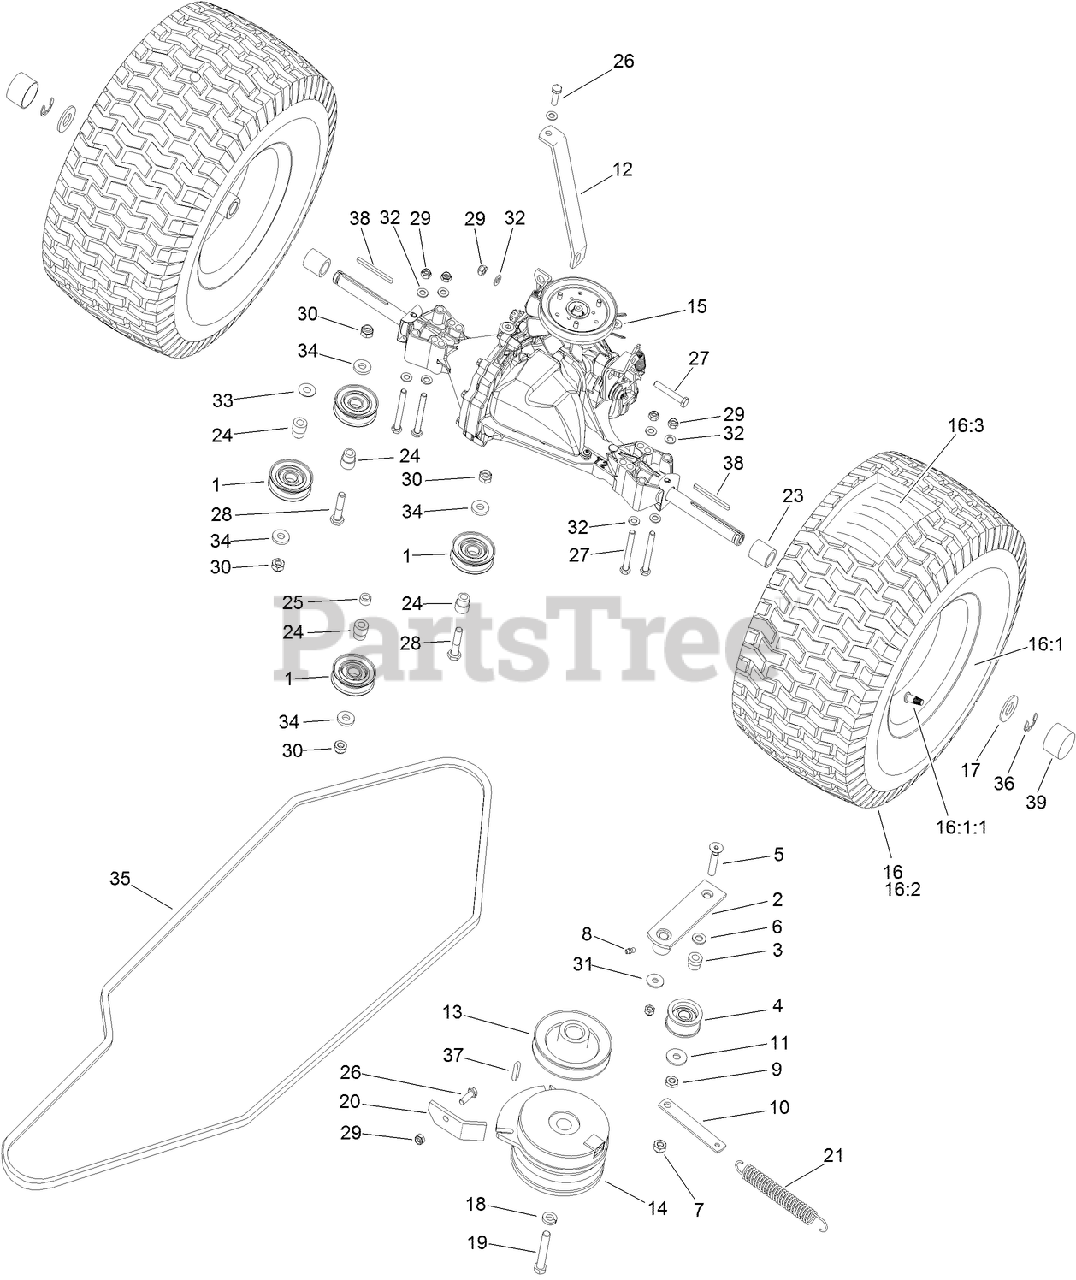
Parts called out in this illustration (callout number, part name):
1	PULLEY-IDLER
2	ARM-IDLER
3	BUSHING-IDLER
4	PULLEY-IDLER
6	WASHER-FLAT
7	NUT-LOCK, NI
8	FITTING-GREASE
9	NUT-HEX
10	BRACKET-TENTION
11	WASHER
12	BRACKET
13	PULLEY-ENGINE
14	CLUTCH-ELECTRIC
15	TRANSMISSION ASM
16	Loose Parts Package
16:1	RIM-REAR
16:1:1	Valve-Tire
17	WASHER
18	WASHER-SPRING, BELLEVILLE
19	SCREW-HH
20	BRACKET-RETAINER
21	SPRING
23	SPACER-AXLE
24	BUSHING
26	SCREW-HH
27	CAPSCREW
28	SCREW-HH
29	NUT-LOCK, NI
30	NUT-LOCK, NI
31	WASHER-PLAIN
32	WASHER-PLAIN
33	Washer
34	WASHER-FLAT
35	V-BELT, TRACTION
36	CLIP-SPRING
37	KEY-SQUARE
38	KEY-SQUARE
39	CAP-HUB
